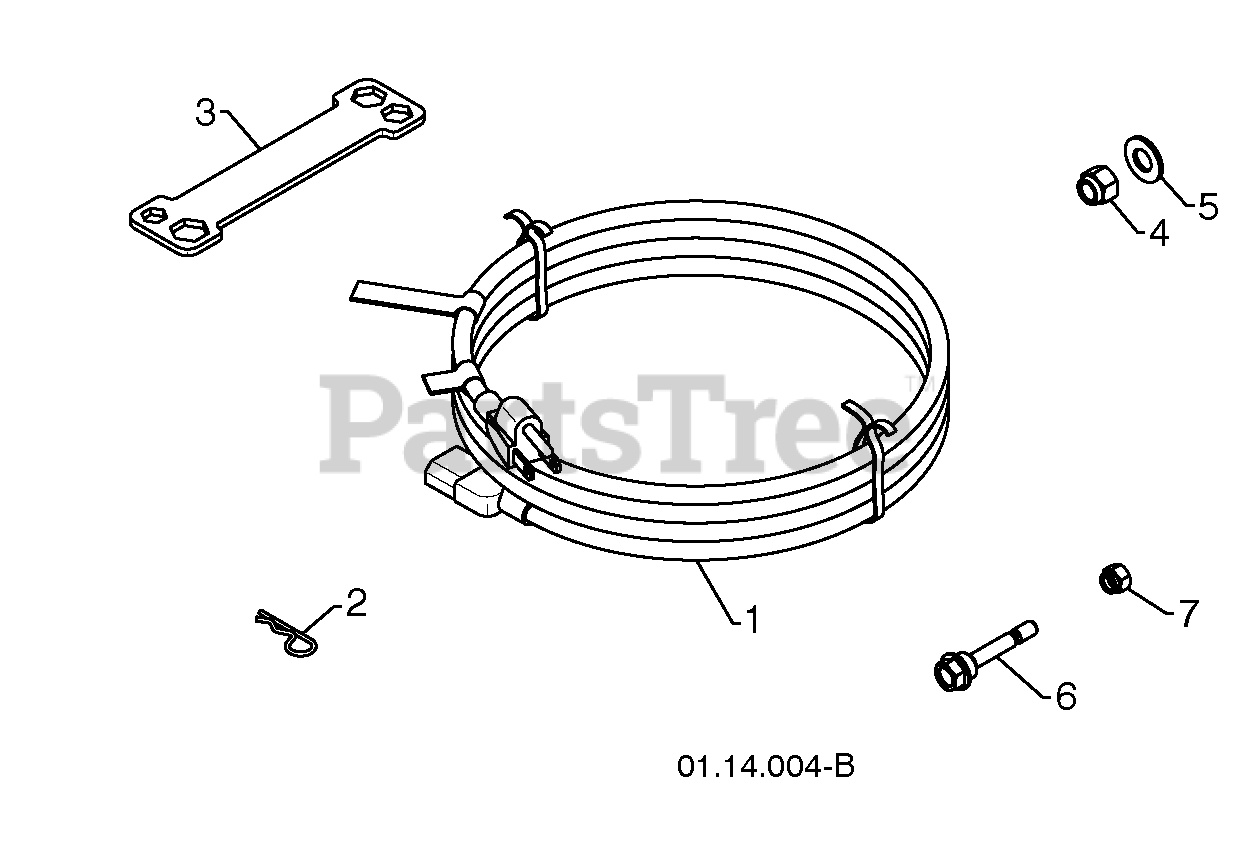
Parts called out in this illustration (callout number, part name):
1	POWER CORD
2	RETAINER PIN
3	WRENCH
4	LOCKNUT 3/8-16
5	WASHER 3/8
6	SHEAR BOLT 1/4-20 X 1-3/4
7	LOCKNUT 1/4-20
